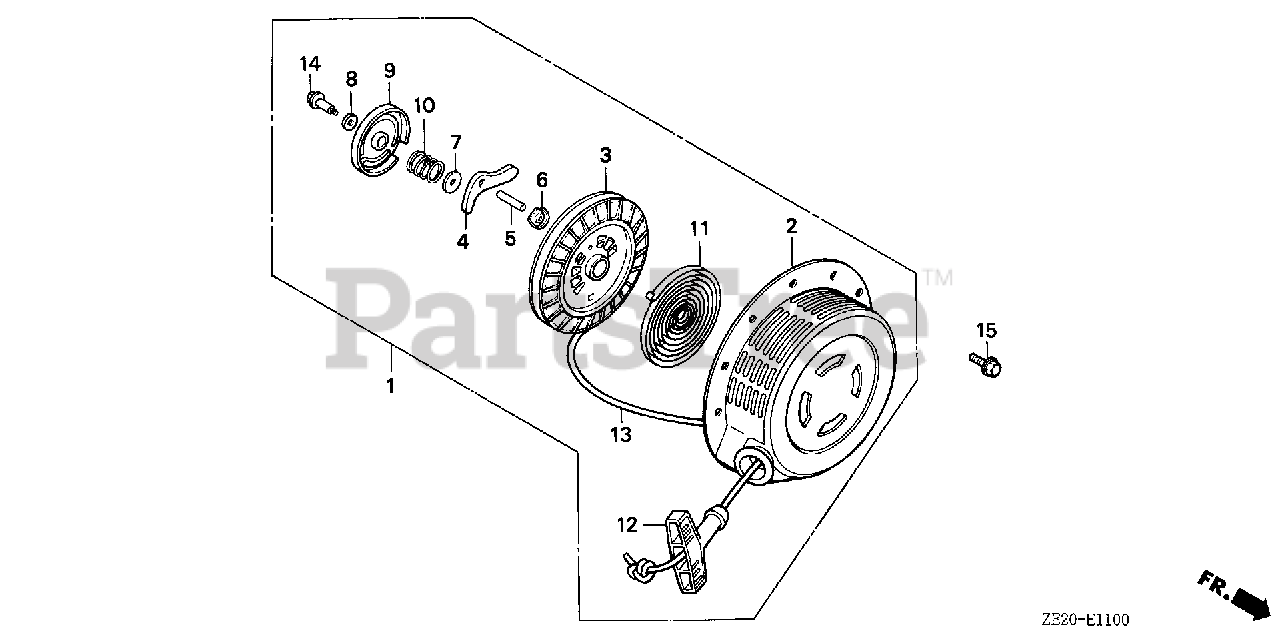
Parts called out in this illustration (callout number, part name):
1	STARTER ASSY., RECOIL *R8* (BRIGHT RED)
2	CASE, RECOIL STARTER *R8* (BRIGHT RED) (NOT AVAILABLE)
3	REEL, STARTER
4	RATCHET, STARTER (NOT AVAILABLE)
5	SHAFT, RATCHET (NOT AVAILABLE)
6	PLATE, GUIDE
7	PLATE A, FRICTION (NOT AVAILABLE)
8	PLATE B, FRICTION
9	COVER, STARTER REEL (NOT AVAILABLE)
10	SPRING, FRICTION
11	SPRING, RETURN
12	GRIP, STARTER
13	ROPE, RECOIL STARTER
14	BOLT, REEL COVER
15	BOLT, FLANGE (6X8)
